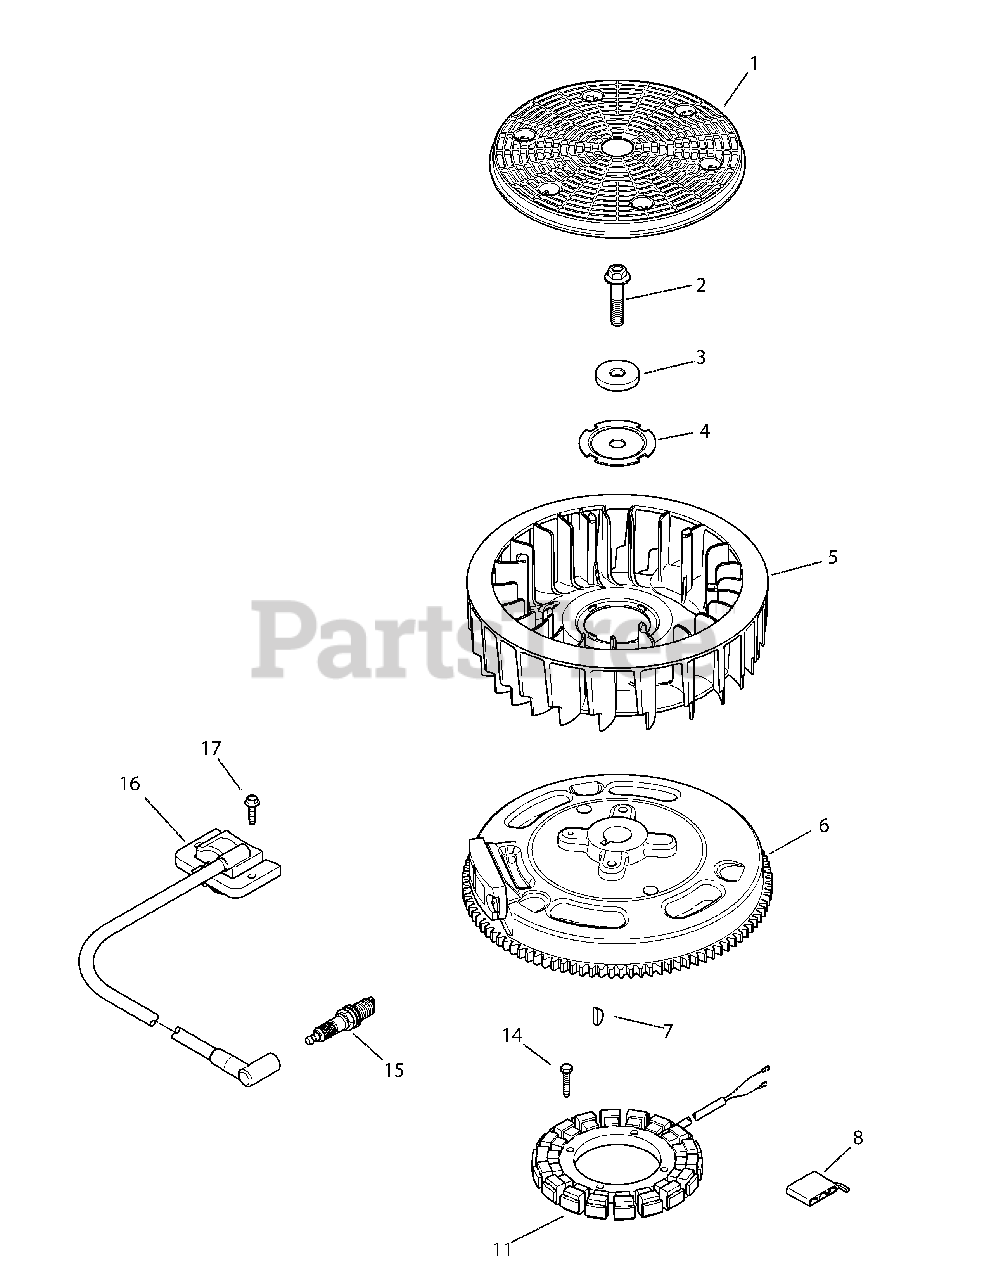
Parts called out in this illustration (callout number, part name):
2	Flg. Screw, M 10 X 1.5 X 45
3	Flat Washer, 13/32
4	Fan Mounting Plate
5	15 Amp Stator Kit Inc. KH-25-452-01-S)
6	Flywheel Assembly (SV730)
6	Flywheel Assembly (SV735)
7	Key, 3/16 X 5/8
11	15 Amp Stator Kit
14	Thd. Frm. Screw, M5 X 0.8 X 25
15	Spark Plug
16	Module Ignition Kit (SV730)
16	Module Ignition Kit (SV735)
17	Flg. Thd. Frm. Screw, M5 X .8 X 20
